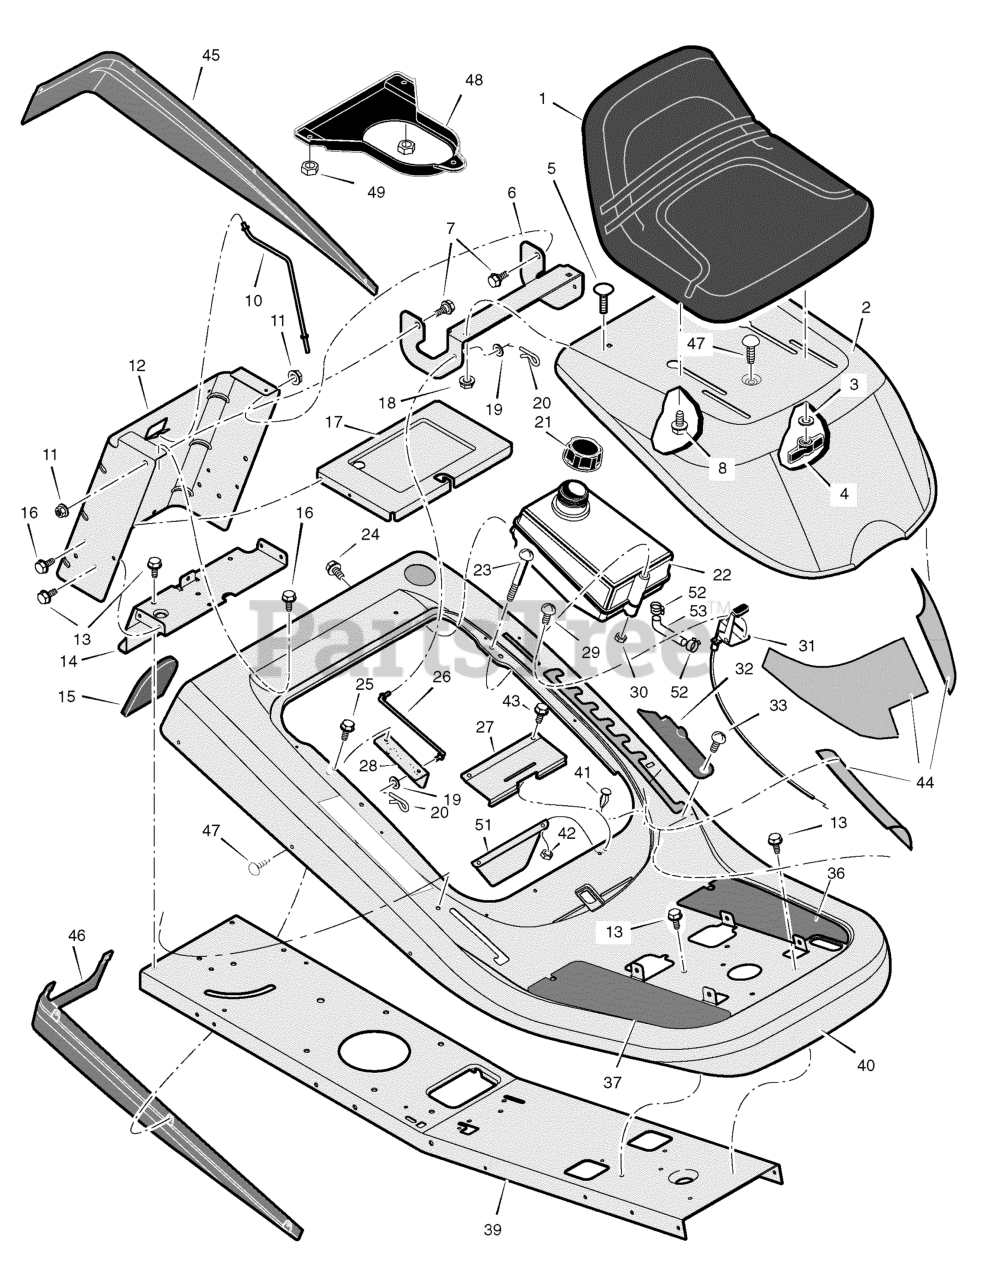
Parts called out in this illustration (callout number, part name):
1	Seat
3	Washer
4	Bolt, Wing
5	Bolt, Carriage
6	Bracket, Hinge
7	Bolt, Shoulder
8	Bolt, Shoulder
10	Rod, Battery
11	Nut, Flange
12	Plate, Rear
14	Plate, Hitch
17	TRAY, Battery
18	Nut, Flange
19	Washer
20	Pin, Cotter
21	Cap, Fuel Tank
22	Tank, Fuel
25	Screw
26	Rod, Hood Prop
27	Spring, Seat Deck
28	Bracket, Prop Rod
30	Nut, NY--Lock
31	Control, Throttle
32	Cover, Detent (Gray)
33	Bolt, Shoulder
36	Footmat, Left
37	Footmat, Right
43	Screw
44	Kit, Foil Heat Shield
45	Trim, Left (Gray)
46	Trim, Right (Gray)
47	Fastener, Panel
49	Nut, Hex 5/16--18
51	Shield, Heat
52	Clamp, Hose
53	Line, Fuel
